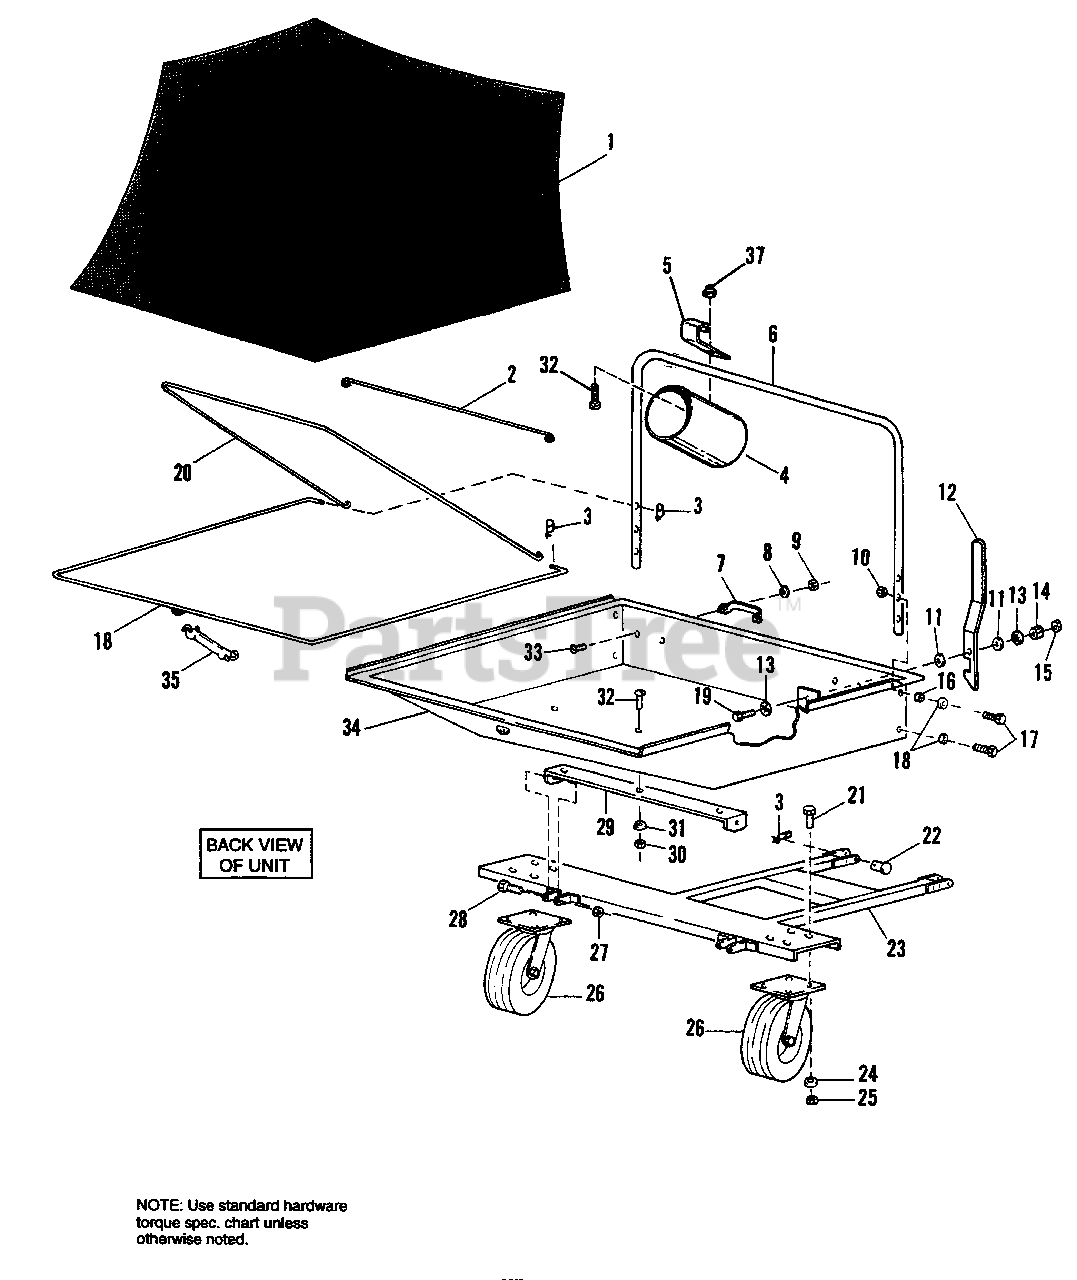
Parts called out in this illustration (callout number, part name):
2	ROD, Straight
3	CLIP, Safety, Hairpin
4	SLEEVE, Plastic, Connecting
5	CLAMP, Sleeve
6	TUBE, Support
7	HANDLE, Lift
8	LOCKWASHER, 1/4
9	NUT, Hex, 1/4-20
10	NUT, Lock, 5/16-18
11	WASHER, Flat, 5/16
12	HANDLE, Latch
13	WASHER, Spring, 5/16
14	NUT, Hex, Full, 5/16-18
15	NUT, Jam, 5/16-18
16	SPACER, Plastic, 5/16
17	CAPSCREW, Hex Hd., 5/16-18 x 1-1/2
19	CAPSCREW, Hex Hd., 5/16-18 x 1-1/4
20	ROD, Support
21	BOLT, Hex, 3/8-16 x 1
22	PIN, 1/2 x 1-1/4
24	WASHER, Flat, 3/8 S.A.E.
25	NUT, Hex Lock, 3/8-16
26	WHEEL, Swivel, 410/350-4
27	NUT, Hex Lock, 1/2-13
28	CAPSCREW, Hex Hd., 1/2-13 x 1-1/4
29	"U" BRACKET
30	NUT, Hex, 5/16-18
31	LOCKWASHER, 5/16
32	BOLT, Slotted, Truss Hd.
33	CAPSCREW, Hex Hd., 1/4-20 x 1/2
35	STRAP, Rubber, 6"
36	CAPSCREW, 1/4-20 x 1/2
37	NUT, Nylon insert, 1/4-20
